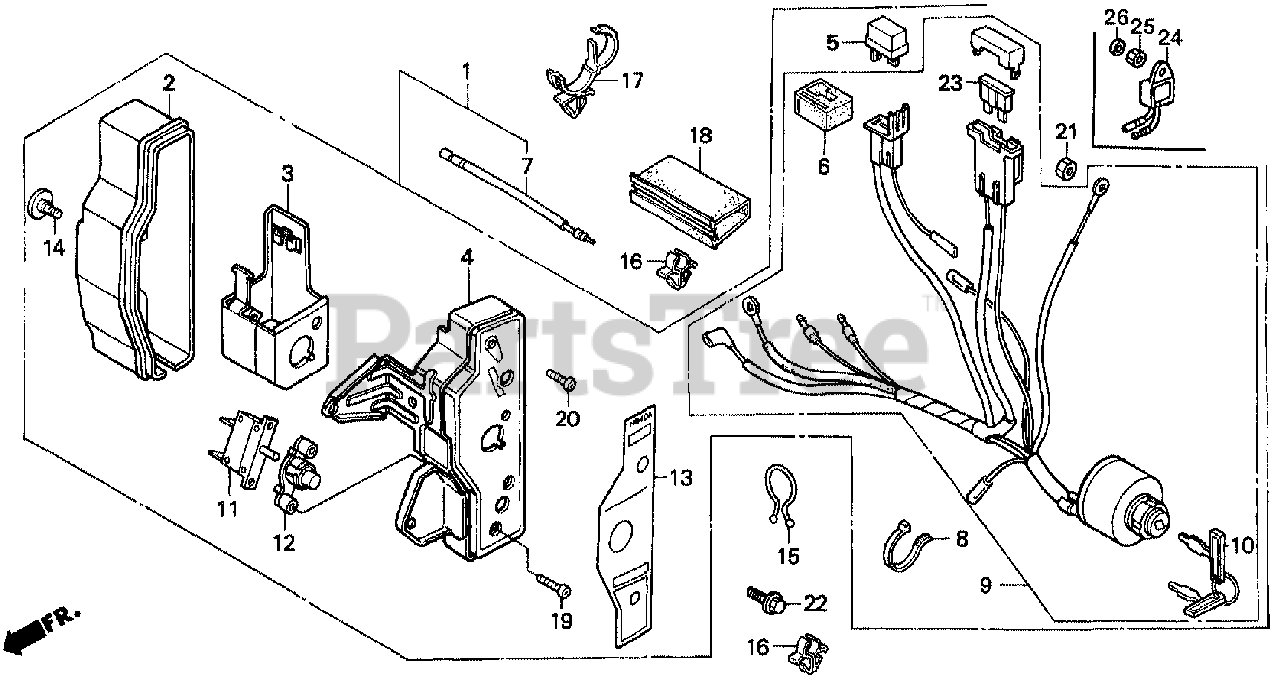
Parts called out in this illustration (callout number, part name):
1	BOX ASSY., CONTROL *R8* (EXTERNAL-ALERT) (BRIGHT RED)
2	CASE, CONTROL
3	BRACKET, CASE MOUNTING
4	PANEL, CONTROL *NH1* (BLACK)
4	PANEL, CONTROL *R8* (BRIGHT RED)
5	RECTIFIER ASSY., SILICON (STANLEY)
6	SUSPENSION, CONNECTOR
7	SUB-HARNESS
8	BAND
9	SWITCH ASSY., COMBINATION
10	KEY
11	PROTECTOR, CIRCUIT (1.0A)
12	LENS ASSY., PROTECTOR
13	PANEL, CONTROL BOX (EXTERNAL)
14	SCREW, SPECIAL (6X12)
15	CLIP, PURSE LOCK
16	CLIP, CORD
17	STRAP, WIRE HARNESS (25MM) (BLACK)
18	TUBE, FASTENER (30)
19	SCREW, PAN (3X12)
20	SCREW, PAN (4X12)
21	NUT, HEX. (4MM) (NOT AVAILABLE)
22	BOLT, FLANGE (6X10)
23	FUSE, BLADE (5A)
24	ALERT UNIT, OIL
25	WASHER, PLAIN (4MM)
26	WASHER, SPRING (4MM)
